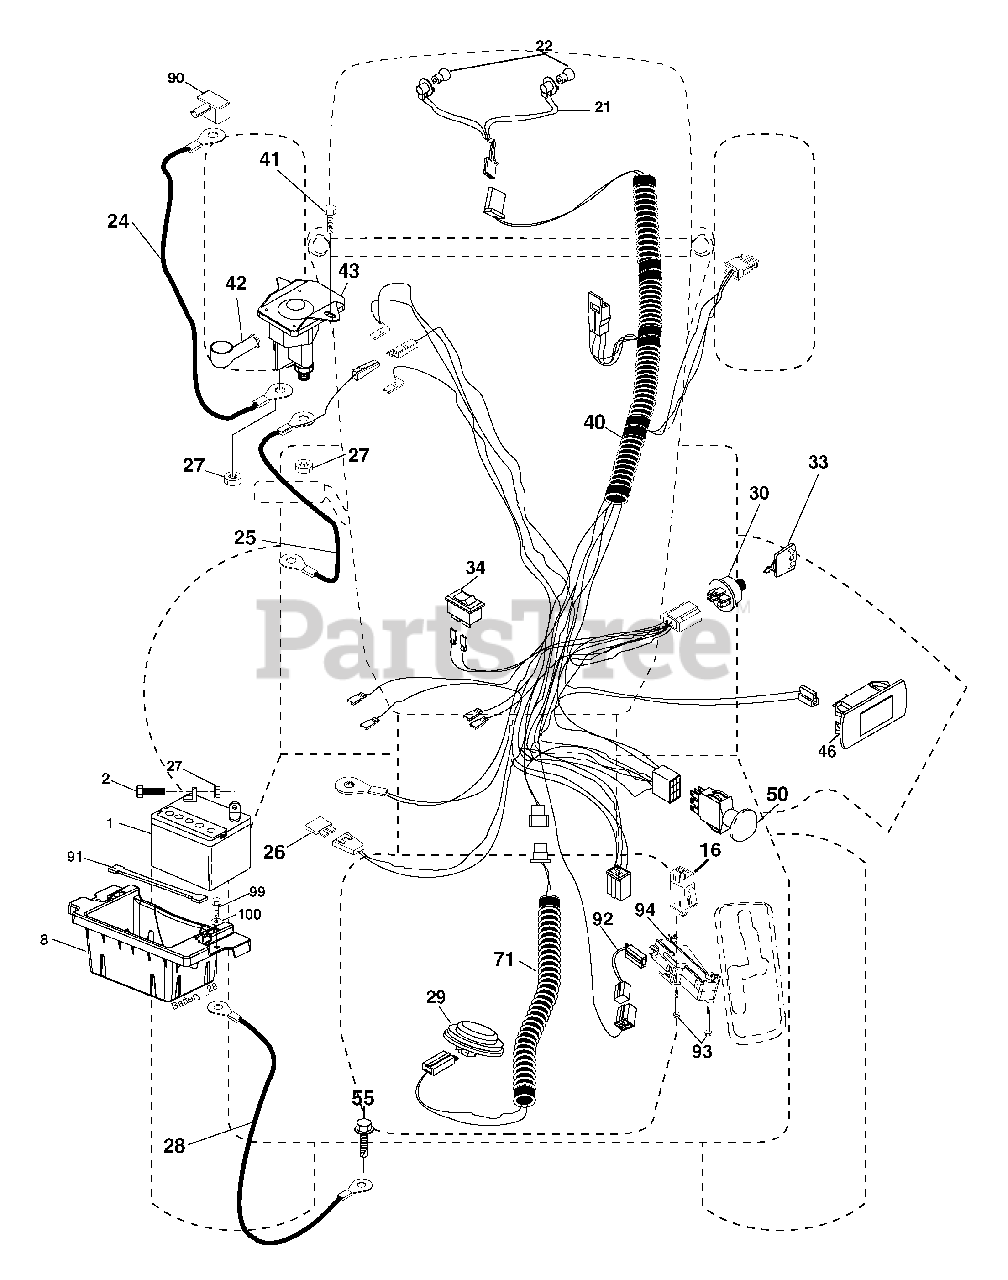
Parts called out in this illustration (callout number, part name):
1	Battery
2	Bolt Hex Hd 1/4-20 unc x 3/4
8	Battery Box
16	Switch Interlock
21	Harness Socket Light
22	Bulb, Light # 1156
24	Cable Battery
25	Cable Starter
27	Nut Keps Hex 1/4-20 unc
28	Cable Ground 21" Blk 6 Ga.
29	Switch Seat
30	Switch Ign
33	Key Ign Molded Generic
34	Switch Light/Reset
40	Harness Ign
41	Screw Thd Cut 1/4-20 x 1/2
42	Cover Terminal Red
43	Solenoid
46	Gauge Hourmeter
50	Switch PTO
55	Screw Thdrol 5/16-18 x 3/4
59	Outlet 12-Volt
71	Harness Ign. Dash
90	Cover Terminal Battery
91	Strap Battery
92	Harness Pigtail Consle ROS
93	Screw Plastite 10-14 x 2.0
94	Module Reverse ROS
99	Screw Hexwsh Thdrol 1/4-20 x 3/4
100	Washer 9/32 x 7/8 x 16 Ga.
